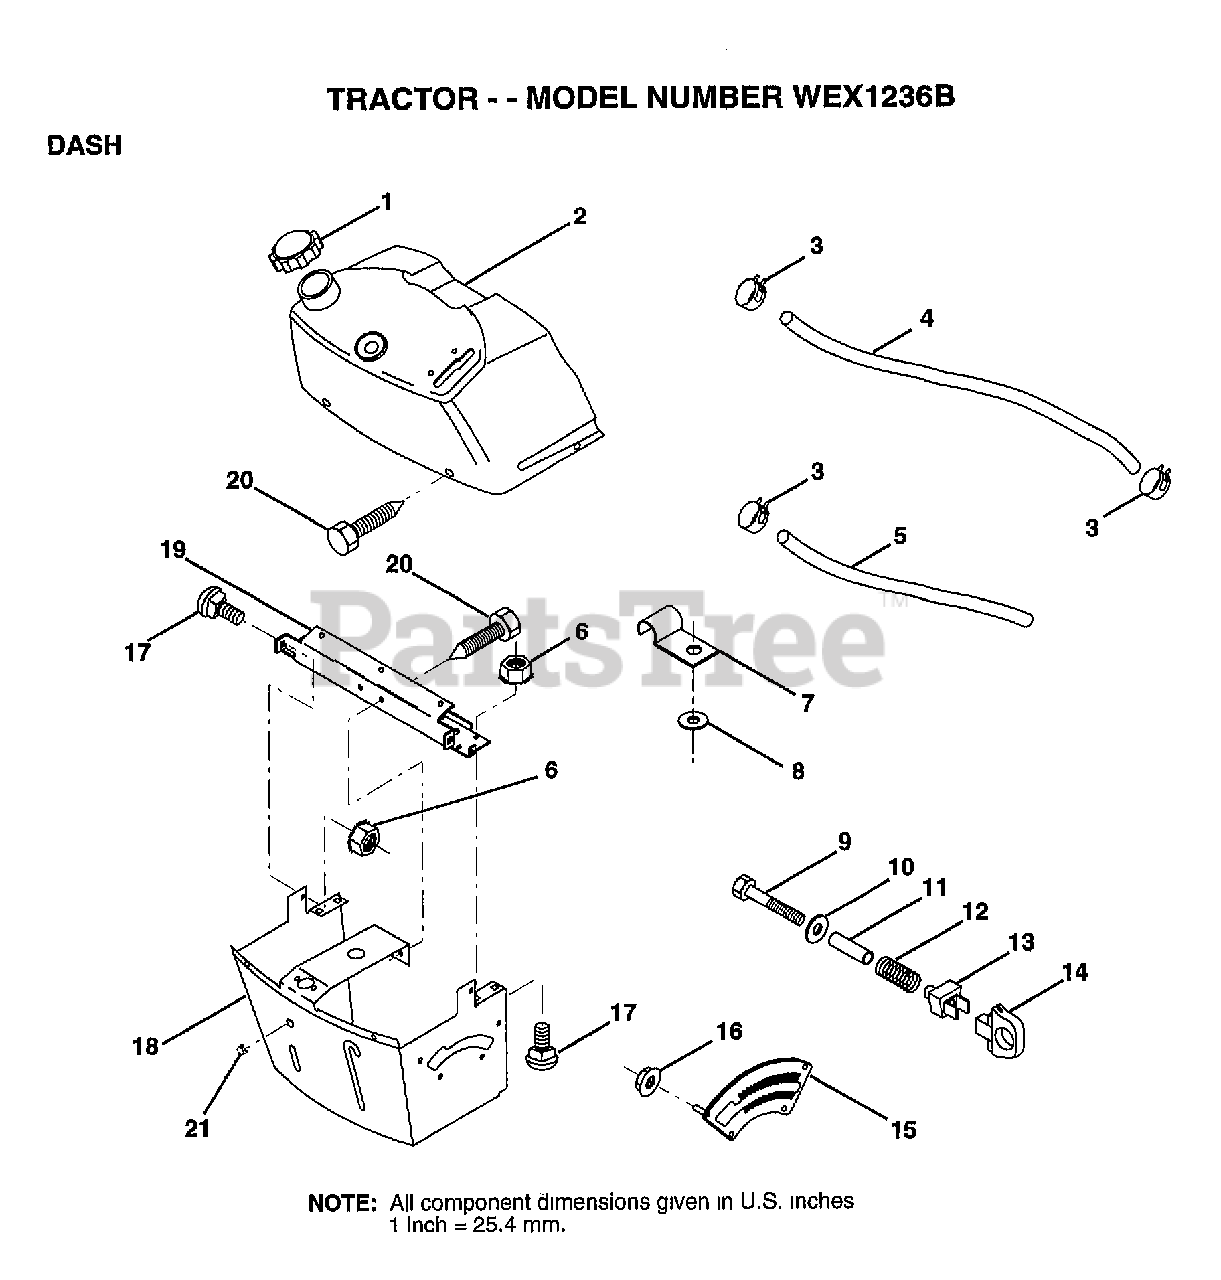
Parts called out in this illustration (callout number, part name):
1	CAP BLK FUEL LR
2	TANK.ASM.DASH.LR
3	HOSE CLAMP
5	FUEL LINE T
6	NUT HXKEP 1/4X20
7	CLIP T
8	WASHER PM
9	BOLT
11	SPACER SPLIT
12	SPRING M
13	"KNOB,HGT RETAINER"
14	KNOB
15	ADJUSTER QUAD
16	NUT
17	BOLT
18	SUPT ASSY DASH
19	CROSS BRACE
20	SCREW.1/4-20X1/2
21	PLUG DOME
